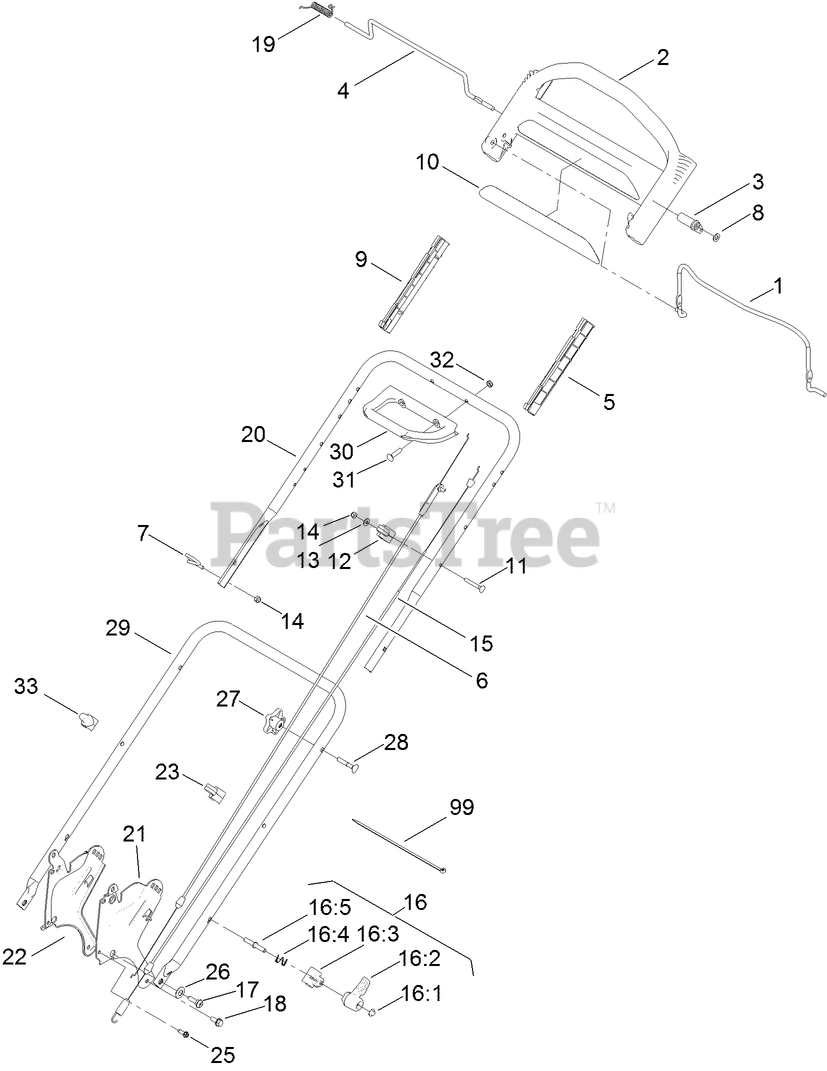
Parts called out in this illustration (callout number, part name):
2	HANDLE-CONTROL
3	LEVER-TRACTION
5	GUIDE-LH
6	CABLE-BRAKE
7	GUIDE-ROPE
8	WASHER-PLAIN
9	GUIDE-RH
10	DECAL-HANDLE
11	SCREW
13	WASHER-FLAT
14	NUT-LOCK, NI
15	CABLE-TRACTION
16	QUICK RELEASE ASM
16:2	LEVER
16:3	ANCHOR-SPRING
16:4	SPRING-COMPRESSION
16:5	ROD-RELEASE
17	SCREW-SHOULDER, BHTF
18	SCREW-THD ROLL, HWH
20	HANDLE-UPPER
21	BRACKET-HANDLE, LH
22	BRACKET-HANDLE, RH
23	GUIDE-CABLE
25	SCREW-HWHTF
26	WASHER-SPRING, CONICAL
27	KNOB-HANDLE
29	HANDLE-LOWER
31	BOLT-CARRIAGE
32	NUT-LOCK, NI
33	GUIDE-ROPE, FLEXIBLE
99	TIE-CABLE
